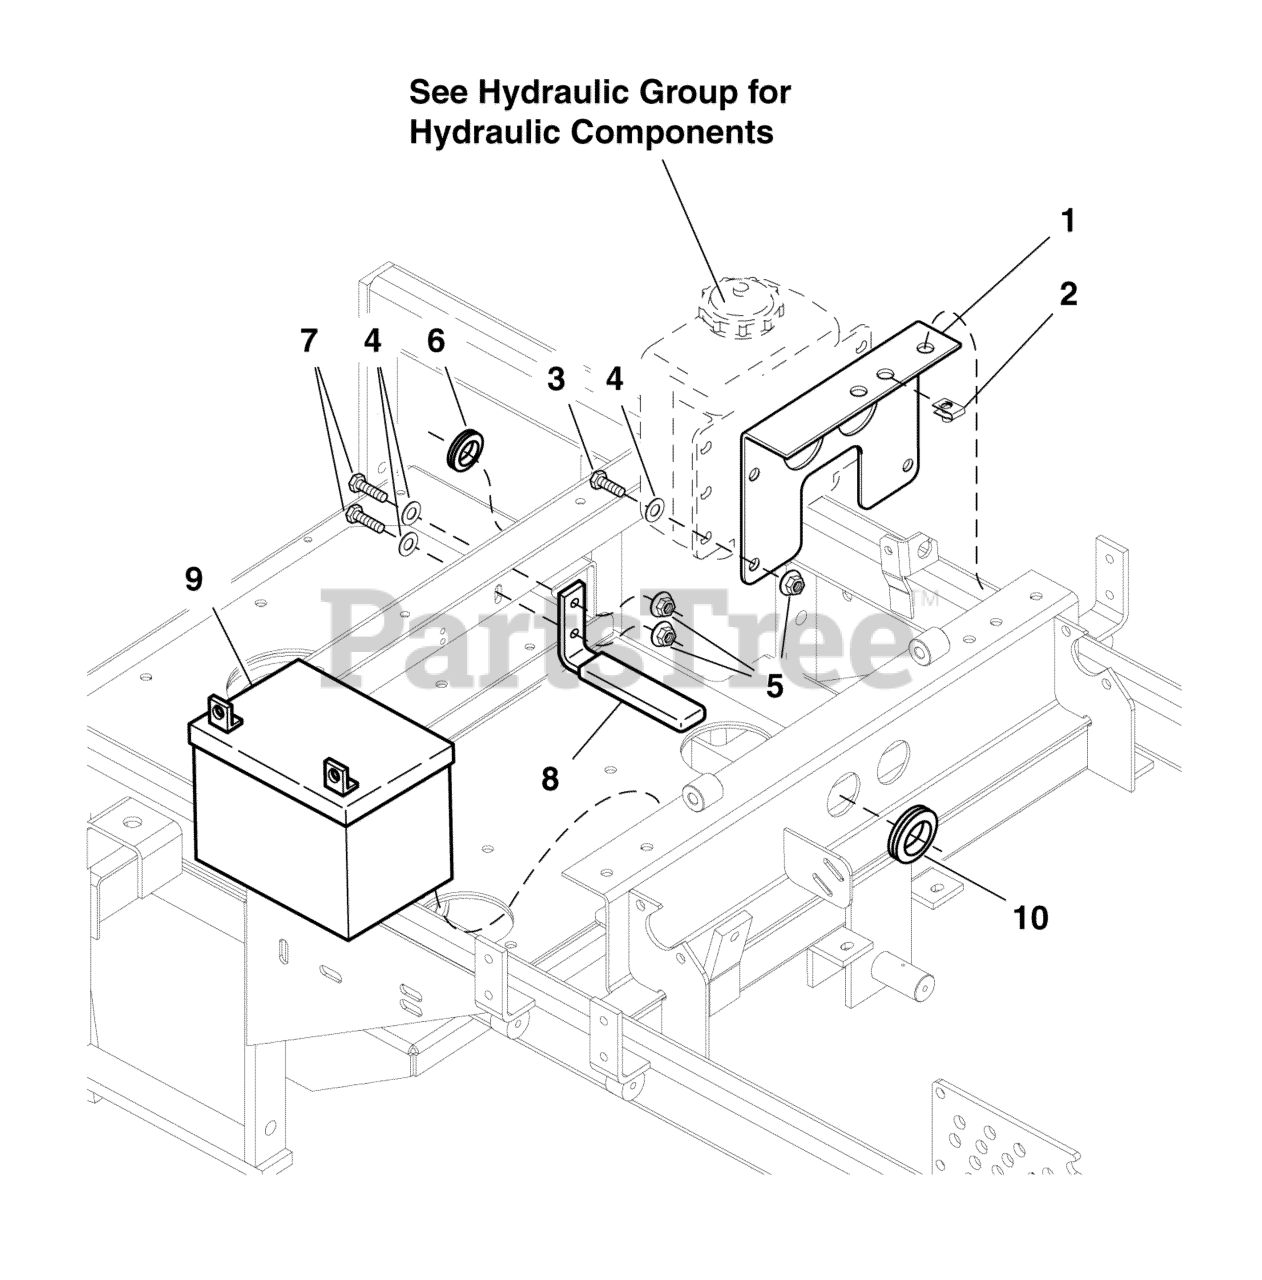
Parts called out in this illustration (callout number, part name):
1	MOUNT, Reservoir
2	BODY CLIP, 3/8-16
3	BOLT, 5/16-18 X 3/4 GD5
4	WASHER, 5/16" SAE
5	NUT, 5/16-18 HEX SERRATED FLANGE (SMALL)
6	GROMMET, 7/8"
7	BOLT, 5/16-18 X 1 GD5 YZ
8	ASSM, BATTERY RETAINER
9	BATTERY, Lawn & Garden, 12V (BCIU1, 340 CCA)
10	GROMMET, 3"
